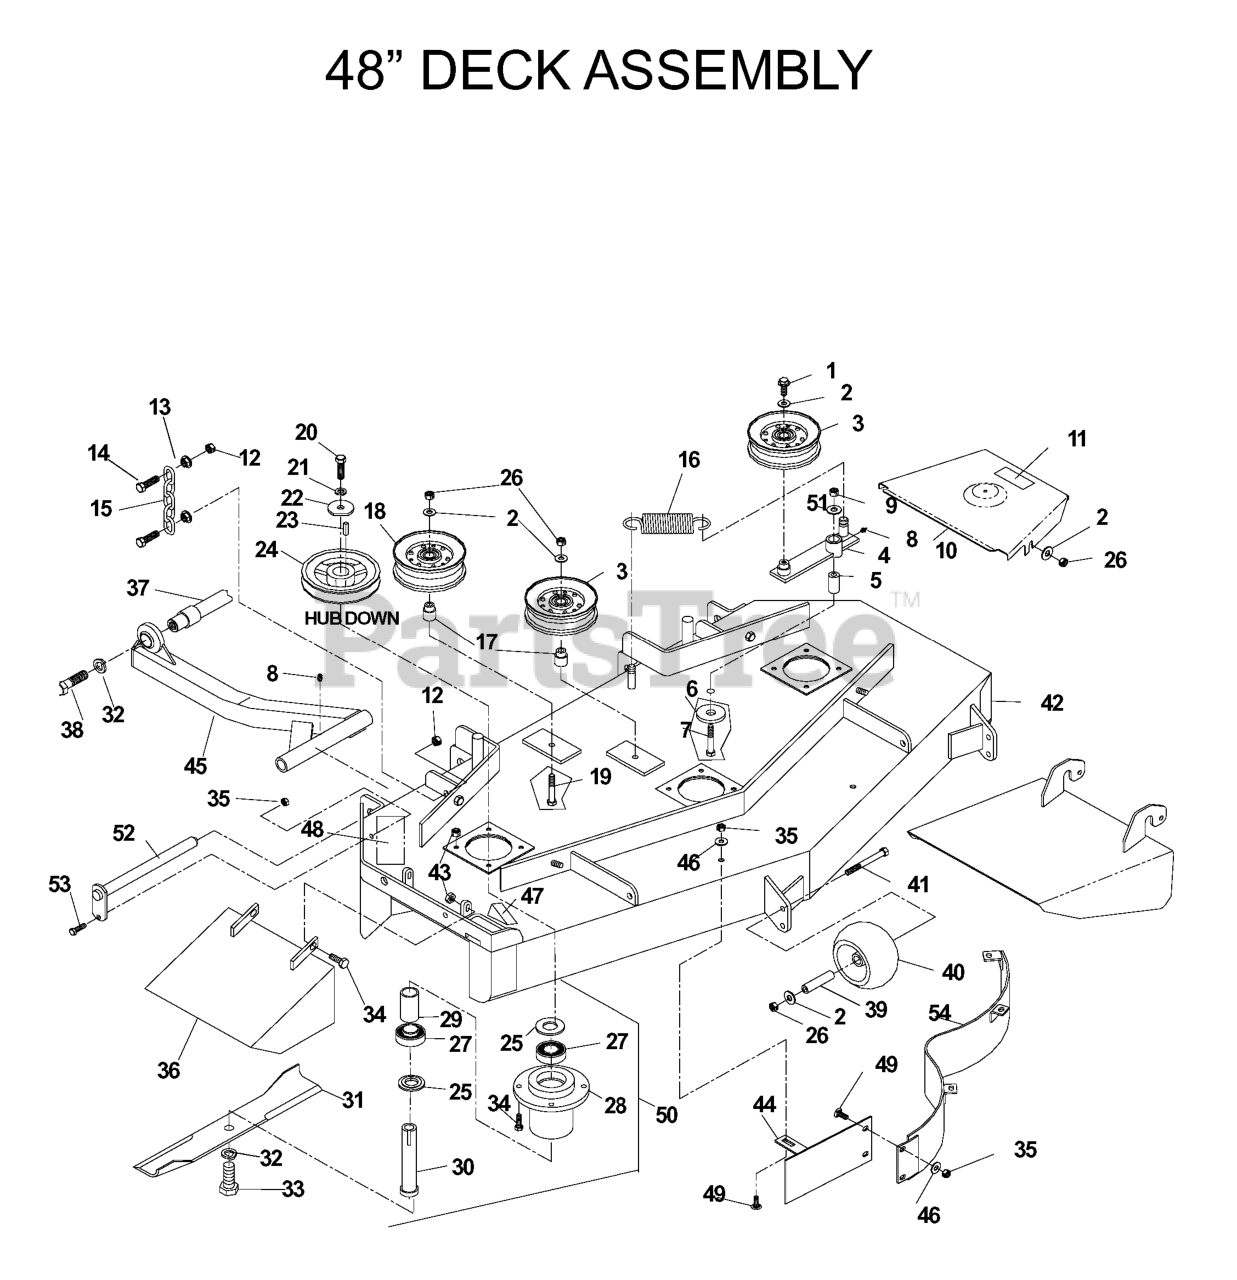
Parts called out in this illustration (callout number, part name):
1	4CS 3/8C X 1 SERRATED HEAD
2	WASHER 3/8 FLAT
3	IDLER PULLEY
5	PIVOT BUSHING
6	WASHER, SUPPORT
7	HCS 1/2C X 3 1/4
8	ZERK
9	NUT 1/2-13 HEX NYLOC ZD
10	BELTSHIELD
11	DECAL, NO STEP
12	NUT 7/16C CENTERLOCK
13	NUT 7/16C WHIZ
14	HCS 7/16C X 1 1/2
15	LIFT CHAIN
17	IDLER BUSHING
18	IDLER PULLEY (TALL)
19	SCREW 3/8C X 2 3/4 HEX CAP
20	HCS 7/16F X 1 1/2
21	WASHER 7/16 LOCK
22	SPINDLE WASHER
23	KEY 1/4 SQ X 1 1/8
25	COMBO SPACER
26	NUT 3/8-16 NYLOC
27	BEARING
28	HOUSING, DIE CAST
30	SPINDLE SHAFT
31	BLADE OEM 16 1/4"
32	LOCKWASHER 5/8
33	HCS 5/8F X 1 1/4
34	HCS 5/16C X 1 1/4
35	NUT 5/16C CENTERLOCK
36	DEFLECTOR CHUTE
37	STRUT MOUNT WELDMENT
38	HCS 5/8C X 2 GR.5
40	ANTI-SCALP ROLLER
41	HCS 3/8C X 3 1/2
42	DECK W/DECALS 48"
43	NUT 5/16 NYLOC
44	CENTER BAFFLE 48"
45	STRUT WLDMT - RT
46	WASHER 5/16 FLAT
47	DECAL, CPSC
48	DECAL, DANGER
49	CARRIAGE BOLT 5/16C X 5/8"
50	HOUSING, COMPLETE
51	WASHER 1/2 FLAT
53	HCS 5/16C X 3/4
54	MAIN BAFFLE - 48" DECK BLK
539103687	DECK BELT 48"
539104621	STRUT SLDMT-LT
